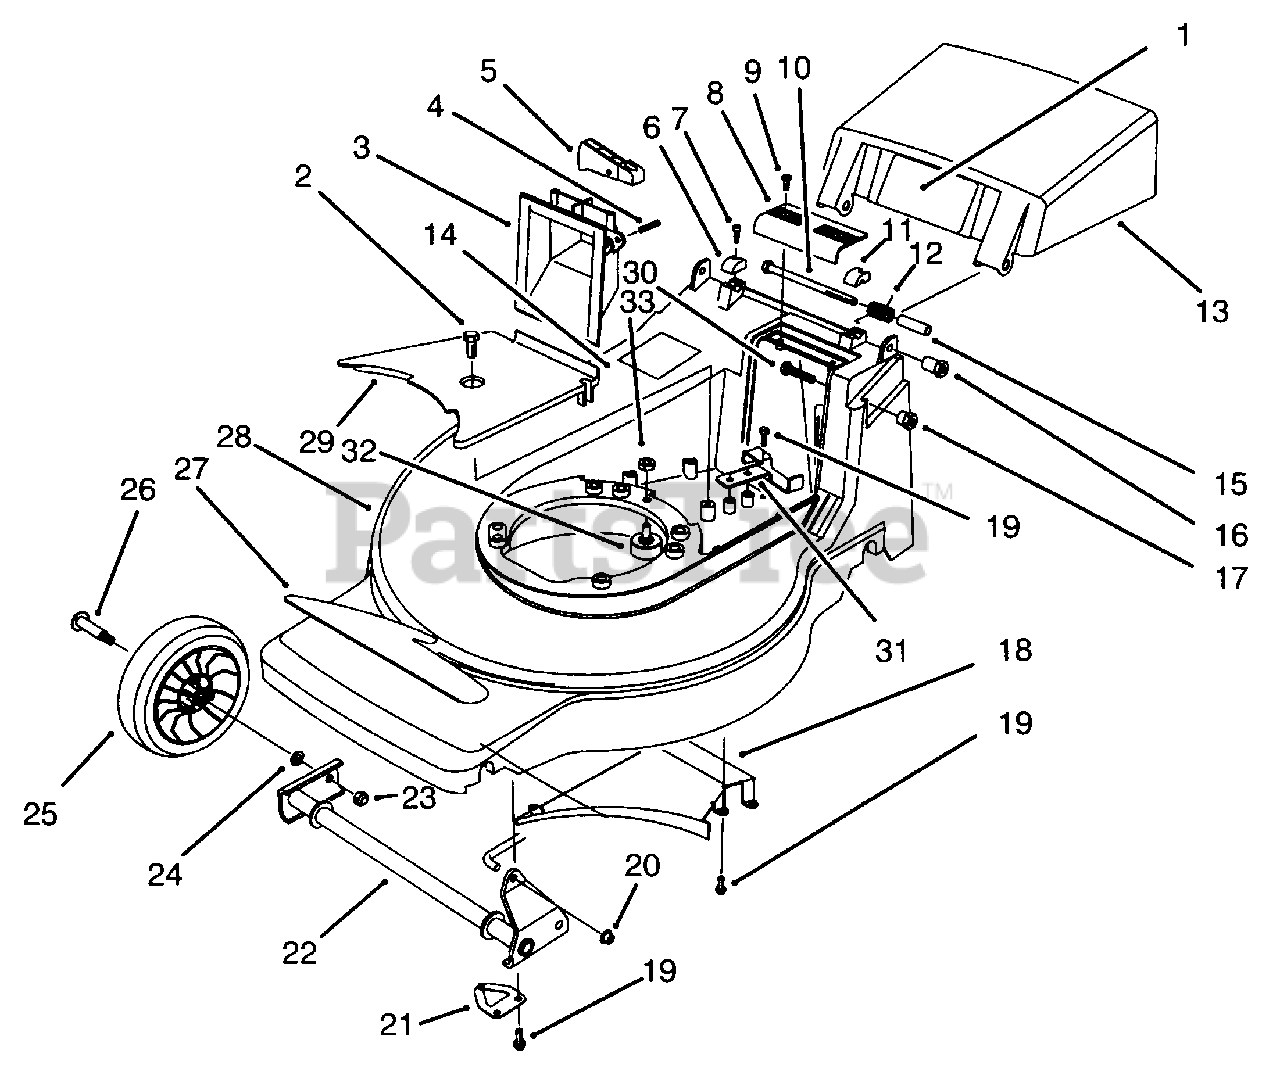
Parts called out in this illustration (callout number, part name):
1	Decal-Danger
2	Screw-Tapping
3	Grip-Lower
4	Pin-Groove
5	Trigger-HOC
6	Cap-R.H. Hinge Bolt
7	Screw-Thread Forming
8	Grip-Upper
9	Screw-Pan Hd. Phillips
10	Screw-Hex Hd. Cap
11	Cap-L.H. Hinge Bolt
12	Spring-Door
13	Door-Discharge
14	Decal-Noise Rating
15	Spacer-Door
16	Spacer-Handle
17	Spacer-Handle
18	Ramp-Discharge
19	Screw-Tapping
20	Nut-Push
21	Retainer-Shaft
22	Pivot-Front
23	Nut-Lock
25	Wheel & Tire Assembly
26	Bolt-Wheel
27	Decal-Deck 450VS
28	Housing (Incl. Ref. #1)
29	Cover-Belt
30	Screw-Hex Hd. Cap
31	Guide-Rear Belt
32	Stud-Ball Bearing
33	Nut-Lock
